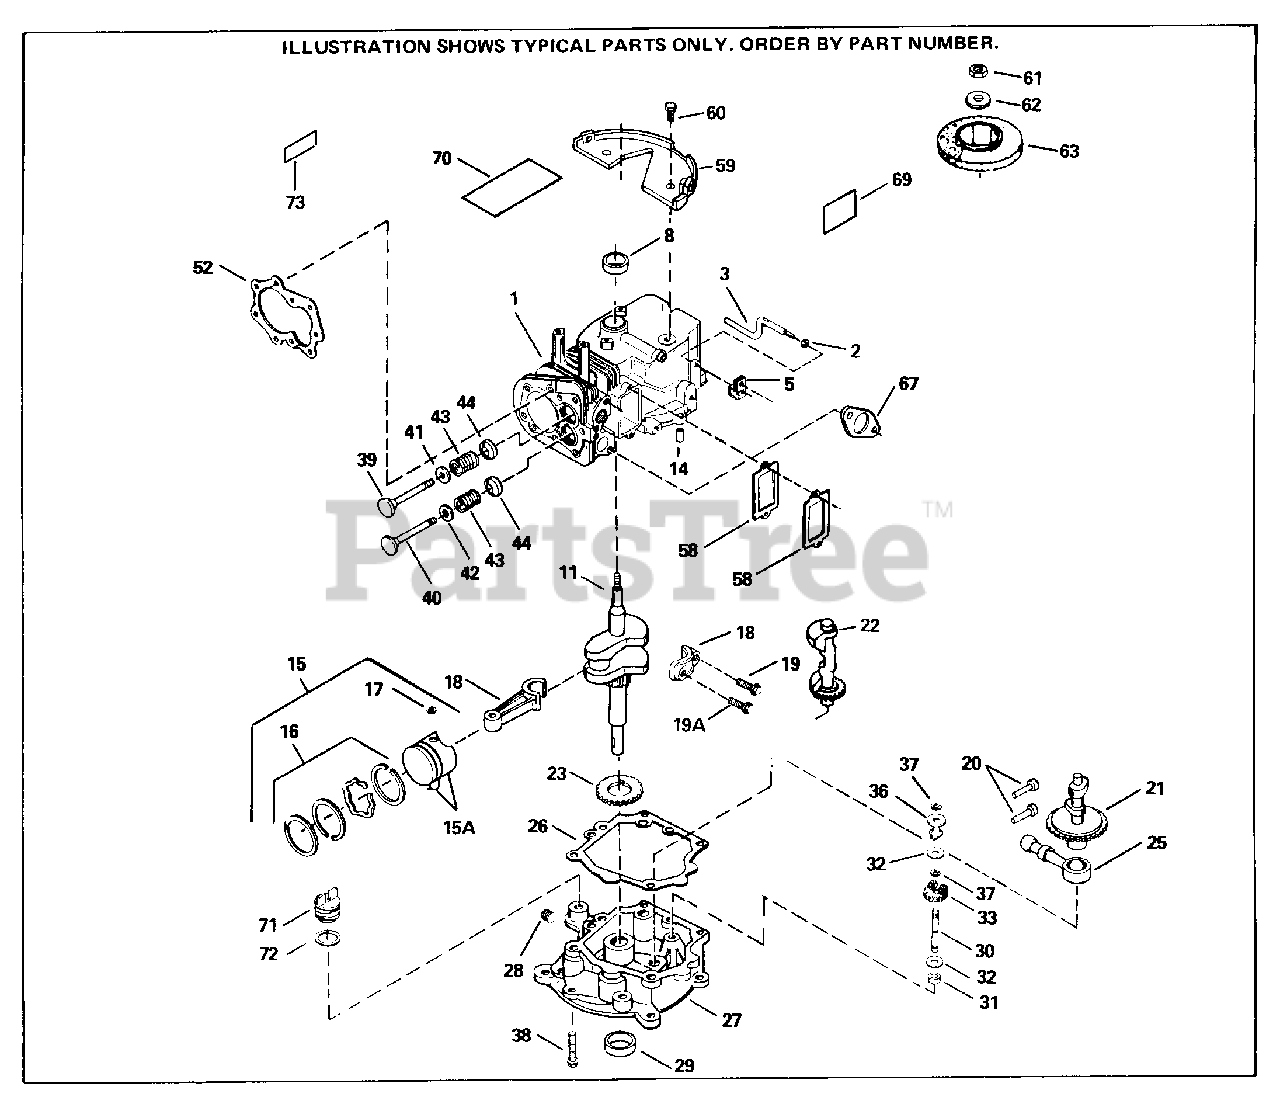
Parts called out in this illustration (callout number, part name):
1	"Cylinder (CI liner)(Incl. 8 & 14) 3-1 /8" Bore
2	Flat Washer
3	Governor Rod
5	Clamp, Governor lever
8	Oil Seal
11	Crankshaft
14	Dowel Pin
15	Piston, Pin & Ring Set (Std.) 3-1/8"B ore
15	Piston, Pin & Ring Set (.010" OS)
15	Piston, Pin & Ring Set (.020" OS)
15A	Piston & Pin Ass'y. (Incl. 17)(Std.) 3-1/8"
15A	Piston & Pin Ass'y. (Incl. 17) .010"O S
15A	Piston & Pin Ass'y. (Incl. 17) .020"O S
16	Ring Set (Std.) (3-1/8" Bore)
16	Ring Set (.010" OS)
16	Ring Set (.020" OS)
17	Piston Pin Retaining Ring
18	Connecting Rod Ass'y. (Incl. 46,47,49 ))
19	Bolt, Connecting rod
19A	Bolt, Connecting rod
20	Lifter, Valve
21	Camshaft (MCR)
22	Weight, Counterbalance
23	Counterbalance Gear
25	Pump Assy., Oil
26	Gasket, Mounting flange
27	Flange, Mounting (Incl. 28, 29 & 30)
28	Plug, Oil drain (3/8-18, sq. hd.)
29	Oil Seal
30	Shaft, Mechanical governor
31	Spacer, Governor gear (Incl. 32)
32	Washer, Flat
33	Governor Gear Ass'y. (Incl. 81)
36	Spool, Governor
37	Retaining Ring
38	Screw, 1/4-20 x 1-3/16"
39	Exhaust Valve (Std.)(Incl. 151)
39	Exhaust Valve (1/32" OS) (Incl. 151)
40	Intake Valve (Std.) (Incl. 44)
40	Intake Valve (1/32" OS) (Incl. 44)
41	Valve Spring Cap
42	Seal Assy., Intake valve
43	Valve Spring
44	Cap, Lower valve spring
52	Gasket, Cylinder head
58	Valve Cover Gasket
67	Intake Pipe Gasket
69	Decal, Instruction
70	Decal, Name (Use as required)
71	Oil Fill Plug (Incl. 312) also availa ble in Packaged Part #740079
72	Oil Fill Plug Gasket
73	Decal, Model & Serial No.
